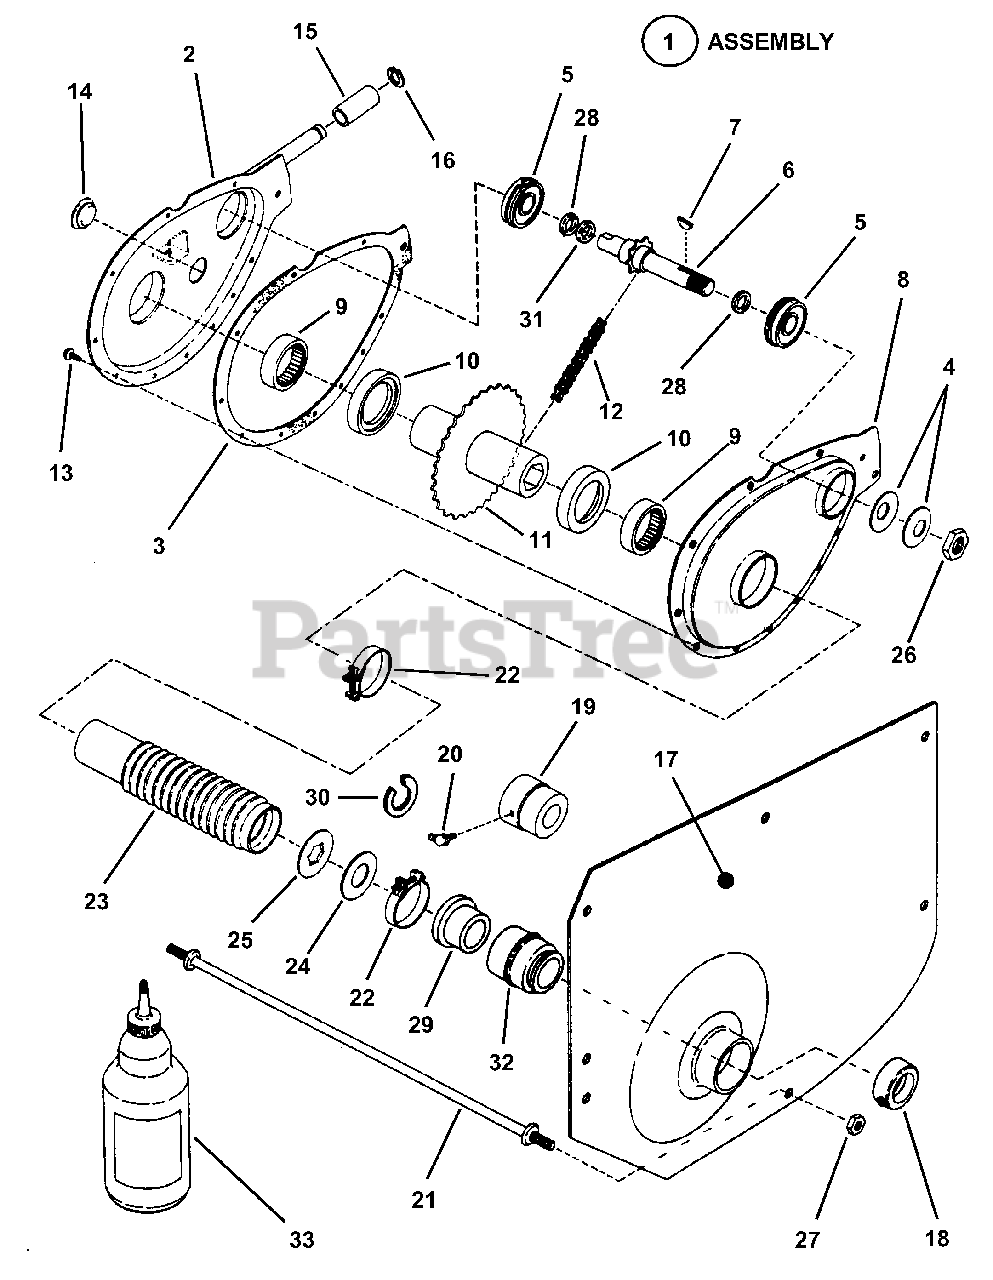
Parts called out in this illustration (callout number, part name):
1	ASSEMBLY, Chain Case
2	CASE, Sprocket
3	GASKET, Case Cover
4	WASHER, Belleville
5	BEARING, Ball
6	SPROCKET & SHAFT
7	KEY, 1/8 x 5/8" Woodruff
8	COVER, Chain Case
9	BEARING, Needle
10	WASHER, Nylon Thrust
11	HUB & SPROCKET
12	CHAIN
13	SCREW, #10-24 x 1/2" Hex Washer Self-Tap (Torx)
14	PLUG, Oil Fill & Check
15	ROLLER
16	RING, 1/2" External Retaining (Heavy Duty)
17	FENDER, Left Hand (25" & 28" Models) (1.628" I.D. hole)
18	COLLAR, Lock
19	BEARING, Left Hand Fender
20	FITTING, Lube
21	ROD, Cross-Tie
22	CLAMP, Boot
23	BOOT, Oil Seal
24	WASHER, Thrust Nylon
25	WASHER, Thrust
26	NUT, 5/8-18 Hex Nyloc
27	NUT, 5/16-24 Hex Flange Lock
28	O-RING
29	SPACER
30	WASHER, Shim
31	WASHER, Shim
32	BALL BEARING, Left Hand Fender (33" Models)
33	GREASE, Transmission
